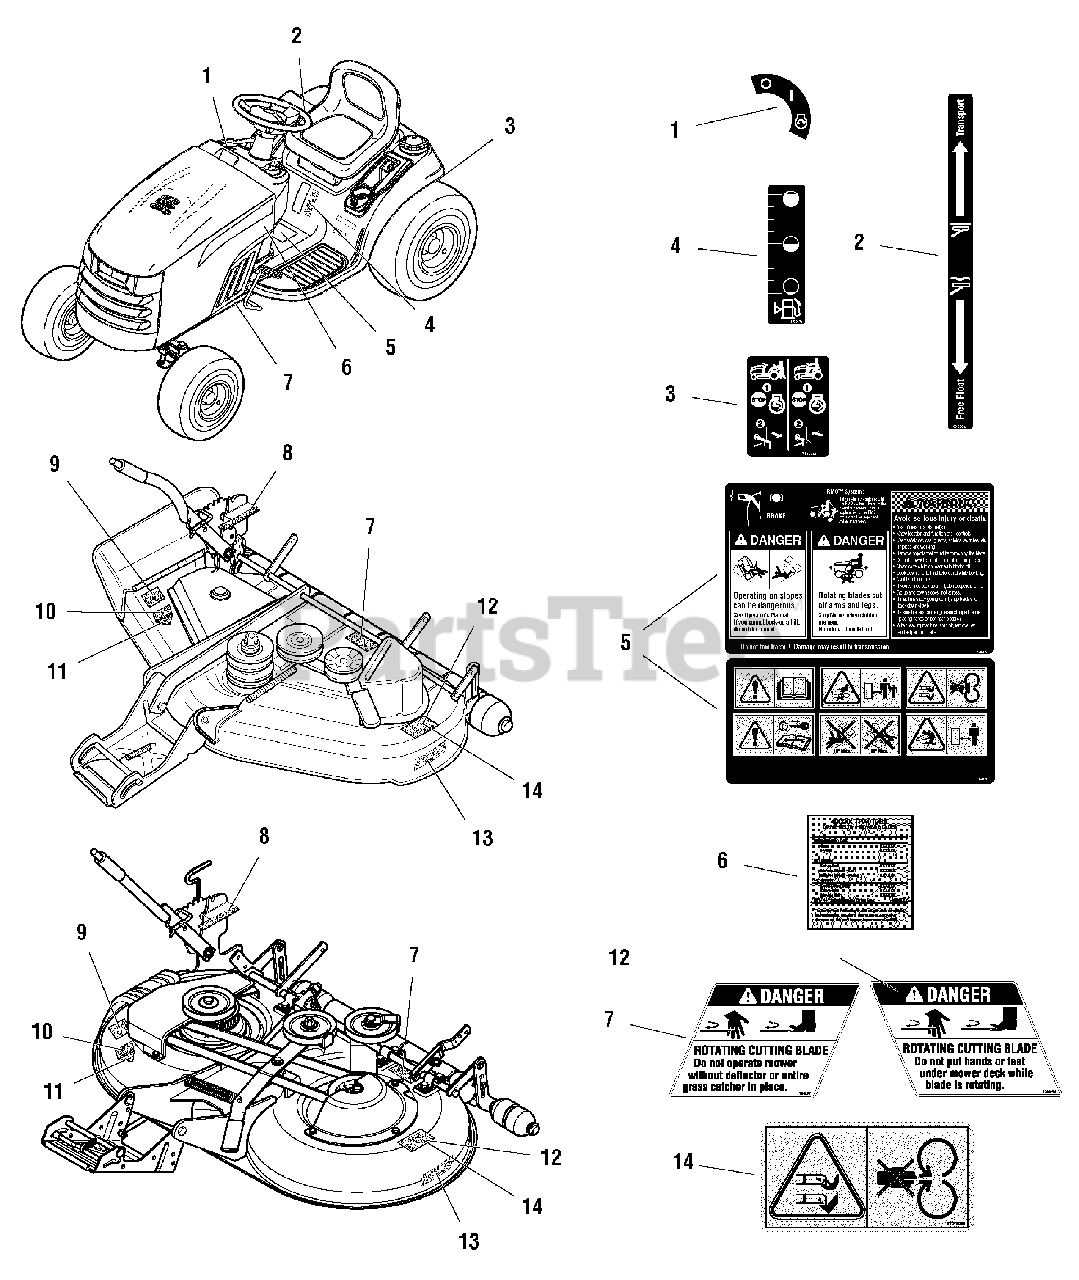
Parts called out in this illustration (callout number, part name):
1	DECAL, Ignition Switch Symbol, White/Black
2	DECAL, Transport/Free Float
3	DECAL, Transmission Tow/ Release Lever
4	DECAL, Fuel Level
5	DECAL, Safety Instructions
5	DECAL, Tunnel
6	DECAL, Belts, Blades
7	DECAL, ID Plate
8	DECAL, Mower Height
9	DECAL, Danger, Chute in Place
10	DECAL, 38"
10	DECAL, 44"
10	DECAL, 50"
11	DECAL, OPEI
12	DECAL, Danger, Hand Under Deck
13	DECAL, Free Floating Mower
14	DECAL, Danger, Rotating Blades
15	DECAL, Patent
